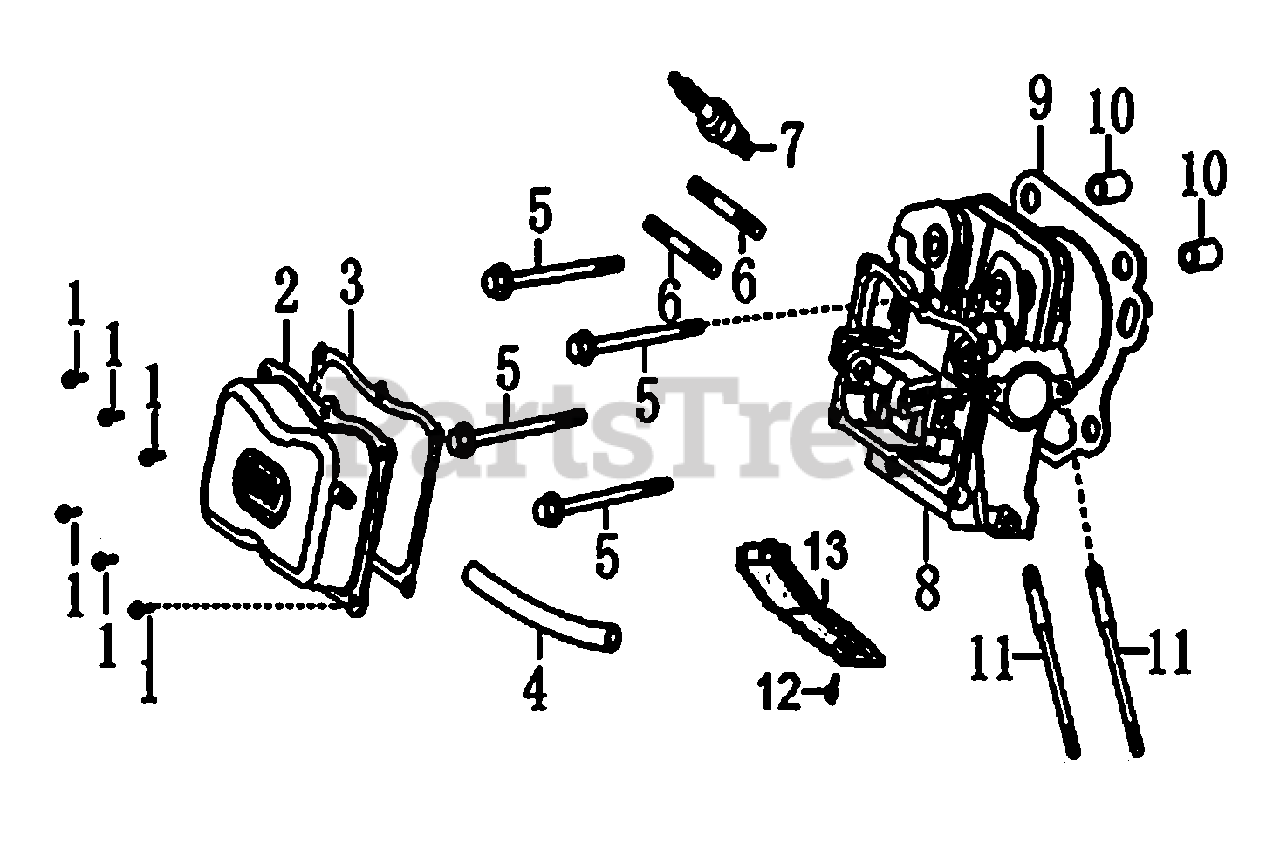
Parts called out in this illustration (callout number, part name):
1	BOLT, FLANGE
2	COVER COMP. HEAD
3	PACKING, HEAD COVER
4	TUBE, BREATHER
5	BOLT, FLANGE, 10X80
6	BOLT, STUD, EXHAUST
7	SPARK PLUG
8	CYLINDER HEAD COMP
9	GASKET, CYLINDER
11	BOLT, STUD, INTAKE
12	BOLT, FLANGE M6X12
